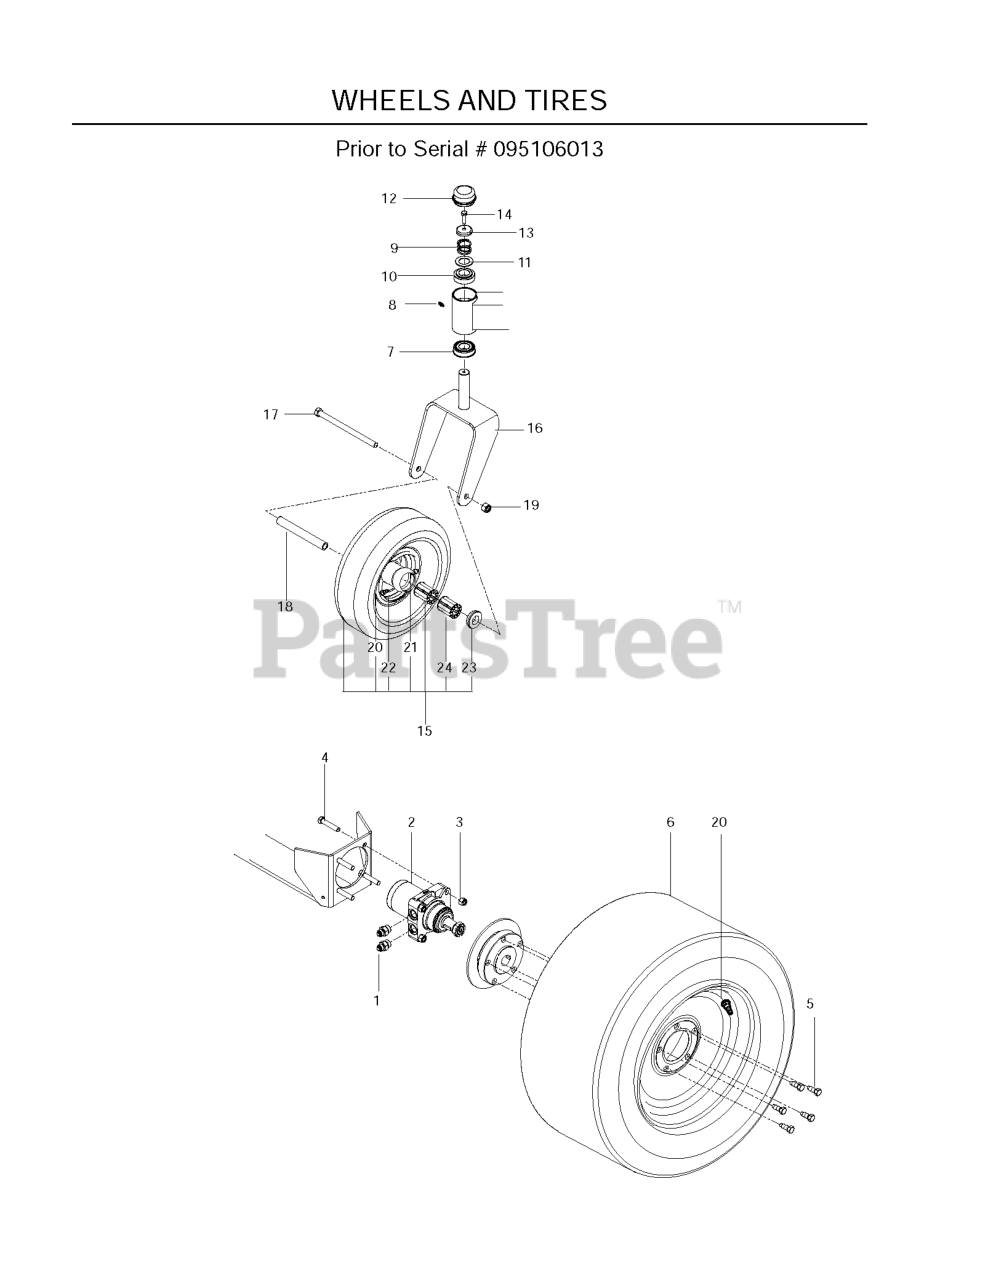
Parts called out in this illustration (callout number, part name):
1	CONNECTOR, STRAIGHT
2	WHEEL MOTOR, TJ
3	NUT 1/2-13 HEX NYLOC ZD
4	HCS 1/2C X 2 3/4
6	WHEEL.R.TS.23X10.5-12.C.MS
7	BEARING FLANGED
8	ZERK, 3/16, DRIVE IN
9	SPRING, CASTER
10	BUSHING, CASTER
11	WASHER, 1.025 ID X 1.64
12	GREASE CAP
13	CASTER.PLUG
14	HCS 5/16C X 1
15	TIRE.ASSEM.13X5-6.SMOOTH.SILVE
16	YOKE, CASTER
17	SCREW 1/2C X 7 1/2 HEX CAP
18	SPACER, CASTER
19	NUT 1/2-13 HEX NYLOC ZD
20	VALVE STEM TR-412
21	ZERK 1/8 NPT
22	RIM
23	BEARING RETAINER
24	ROLLER BEARING
